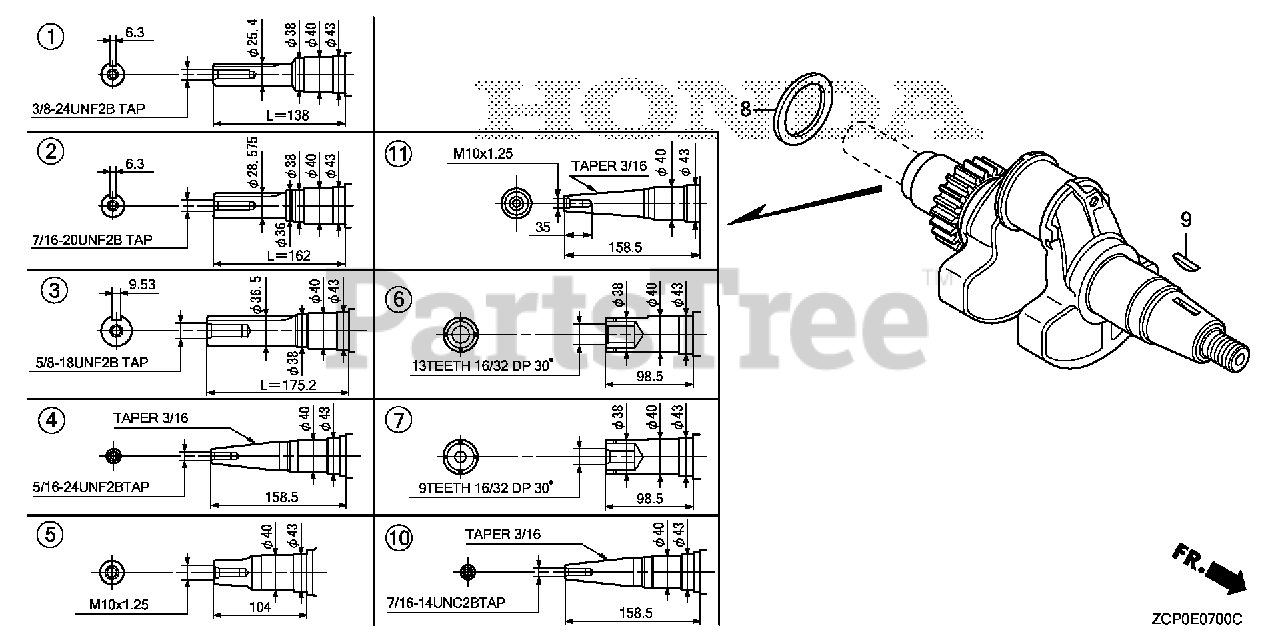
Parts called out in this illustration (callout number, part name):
2	CRANKSHAFT (L=162)
8	WASHER, CRANKSHAFT THRUST
9	KEY, SPECIAL WOODRUFF (25X18)
